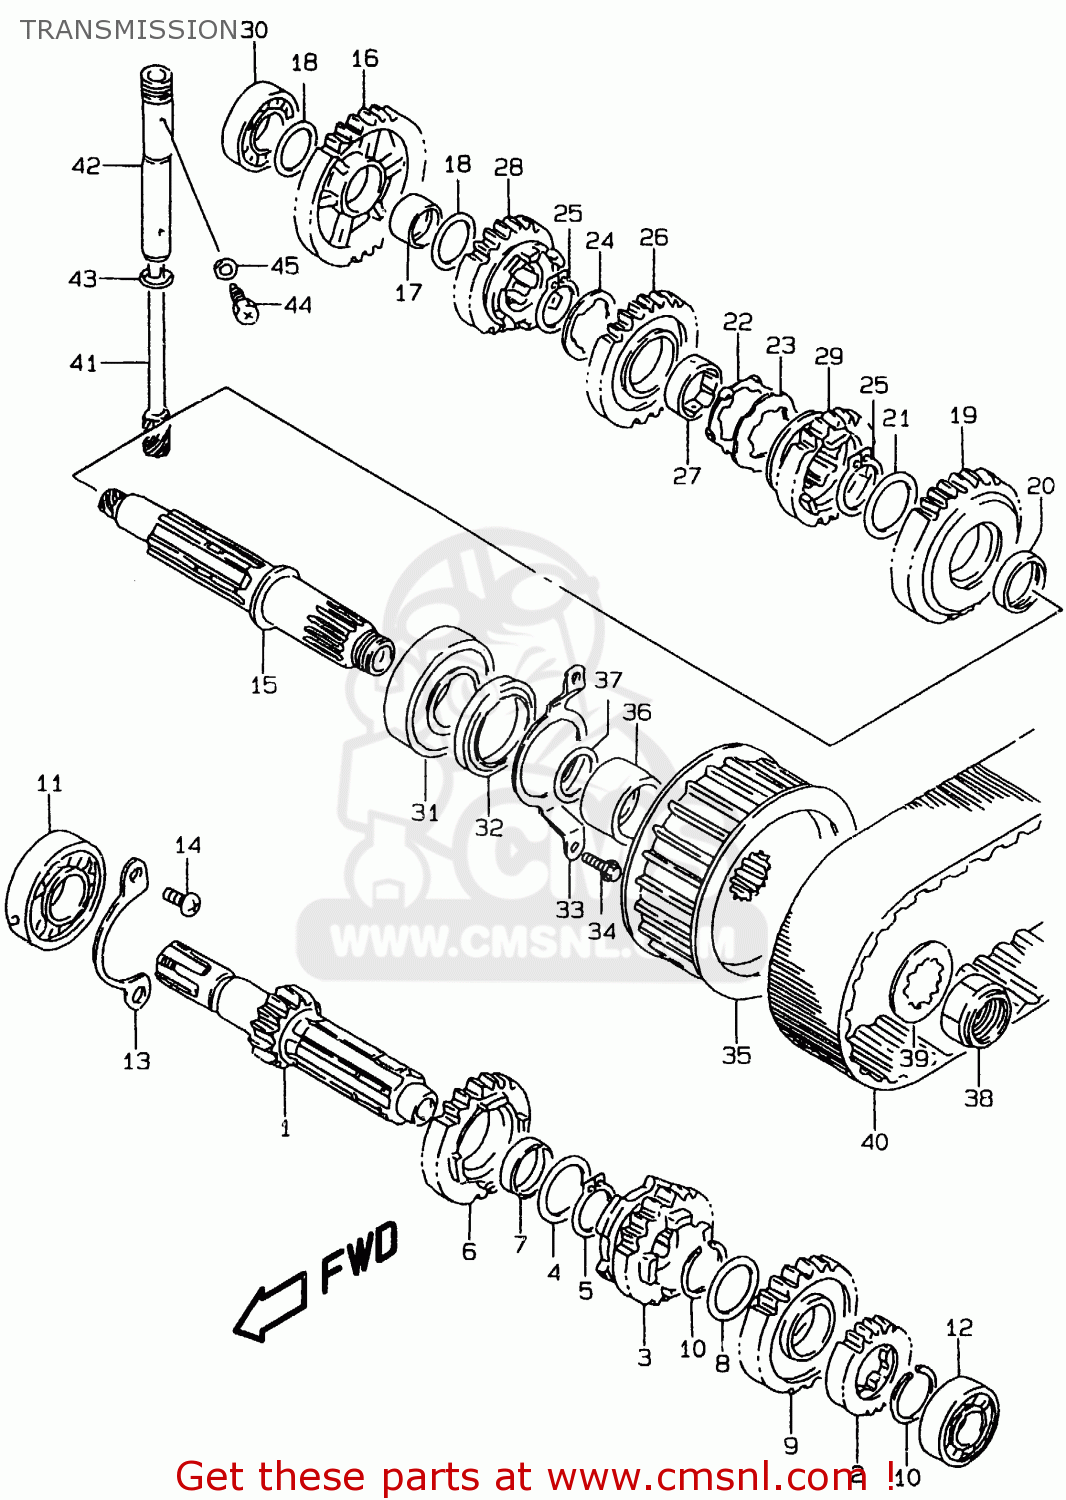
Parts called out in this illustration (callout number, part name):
1	SHAFT,COUNTER(NT:15)
2	GEAR,2ND DRIVE
3	GEAR,THIRD DRIVE
4	WASHER
5	RING,SNAP
6	GEAR,4TH DRIVE
7	BUSHING 25X29X10
8	WASHER,LOCK
9	GEAR,5TH DRIVE
10	CIRCLIP
11	BEARING(22X56X16)
12	BEARING(17X40X12)
13	RETAINER,CNTR SHAFT BEARING
14	SCREW
15	SHAFT,DRIVE
16	GEAR,1ST DRIVEN(NT:35)
17	BUSH(20X24X13)
18	WASHER
19	GEAR,2ND DRIVEN
20	BUSH(25X29X8)
21	WASHER
22	WASHER
23	WASHER,LOCK
24	WASHER,LOCK
25	RING,SNAP
26	GEAR,3RD DRIVEN
27	BUSHING
28	GEAR,4TH DRIVEN(NT:22)
29	GEAR,5TH DRIVEN
30	BALL BEARING 20X42X12
31	BALL BEARING 25X62X17
32	SEAL,OIL(36X50X6)
33	RETAINER,DRIVE SHAFT OIL SEAL
34	BOLT
35	PULLEY,FR
36	SPACER,FR PULLEY
37	O RING(D:2.4,ID:23.7)
38	NUT
39	WASHER,LOCK
40	BELT,DRIVE
41	GEAR,SPEEDOMETER DRIVEN
42	SLEEVE,TACHOMETER DRIVEN GEAR
43	O RING(D:1.3,ID:9.6)
44	BOLT
45	GASKET(6.2X11X1).2 (NAS)
